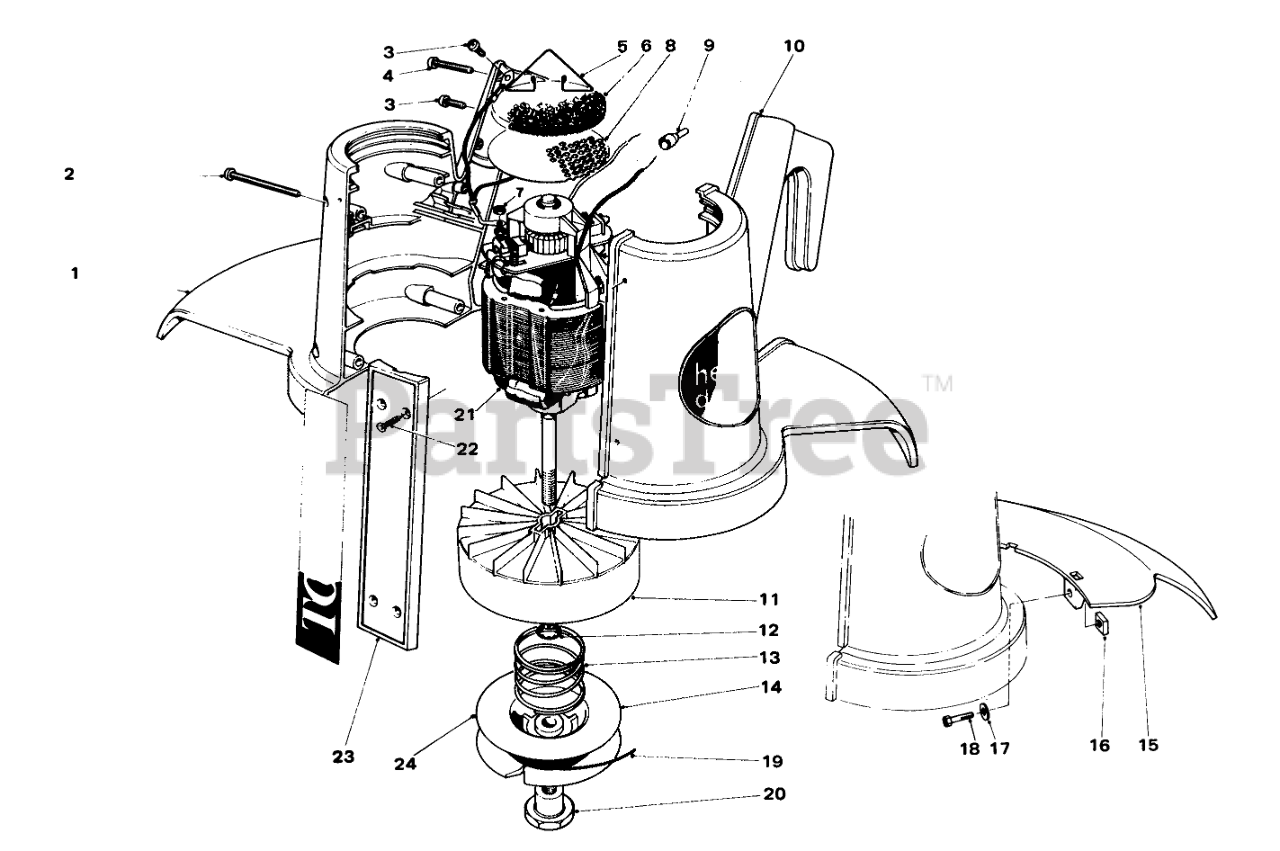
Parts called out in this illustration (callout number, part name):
2	SCREW-PLASTITE
7	NUT-HEX
9	CONNECTOR WIRE JOINT
12	NUT-PUSH IN
16	NUT-SQUARE
17	WASHER-LOCK
18	SCREW-HH
19	50-Coil.065" Cutting Line
